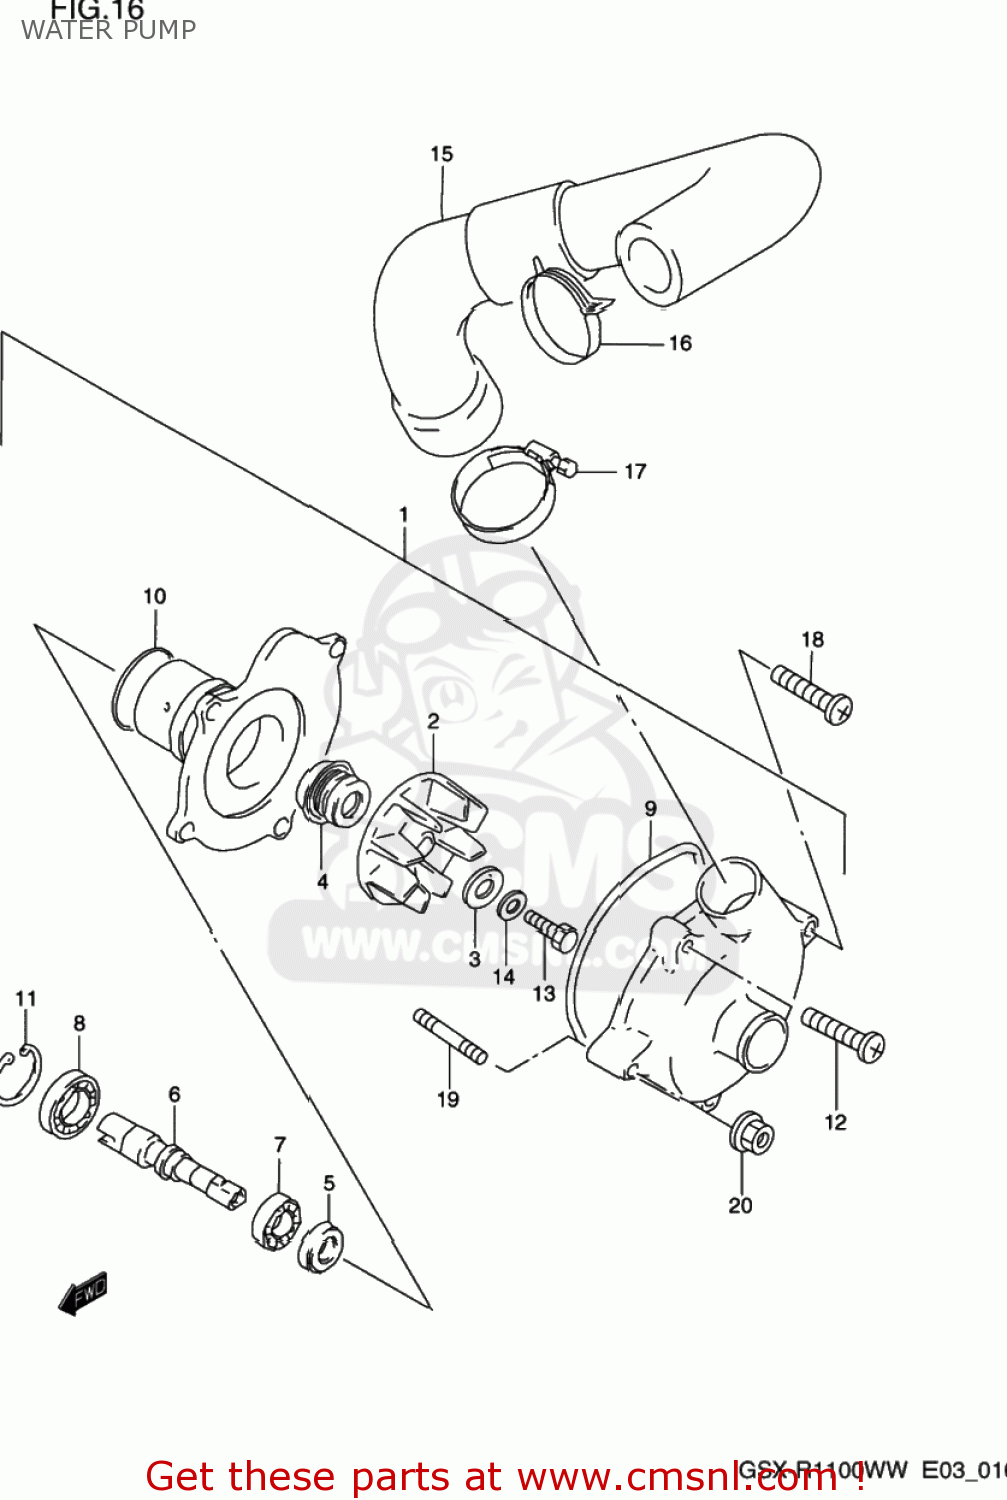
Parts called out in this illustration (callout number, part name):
1	PUMP ASSY,WATER
2	IMPELLER
3	GASKET(6X15X2.2) (NAS)
4	SEAL,MECHANICAL
5	OILSEAL
6	SHAFT
7	BEARING
8	BEARING(12X28X8)
9	O RING
10	O RING,WATER PUMP HOLDER
11	CIRCLIP
12	SCREW
13	BOLT(6X13)
14	WASHER
15	HOSE,WATER PUMP OUTLET
16	CLAMP
17	CLAMP
18	SCREW
19	BOLT,STUD
20	NUT
